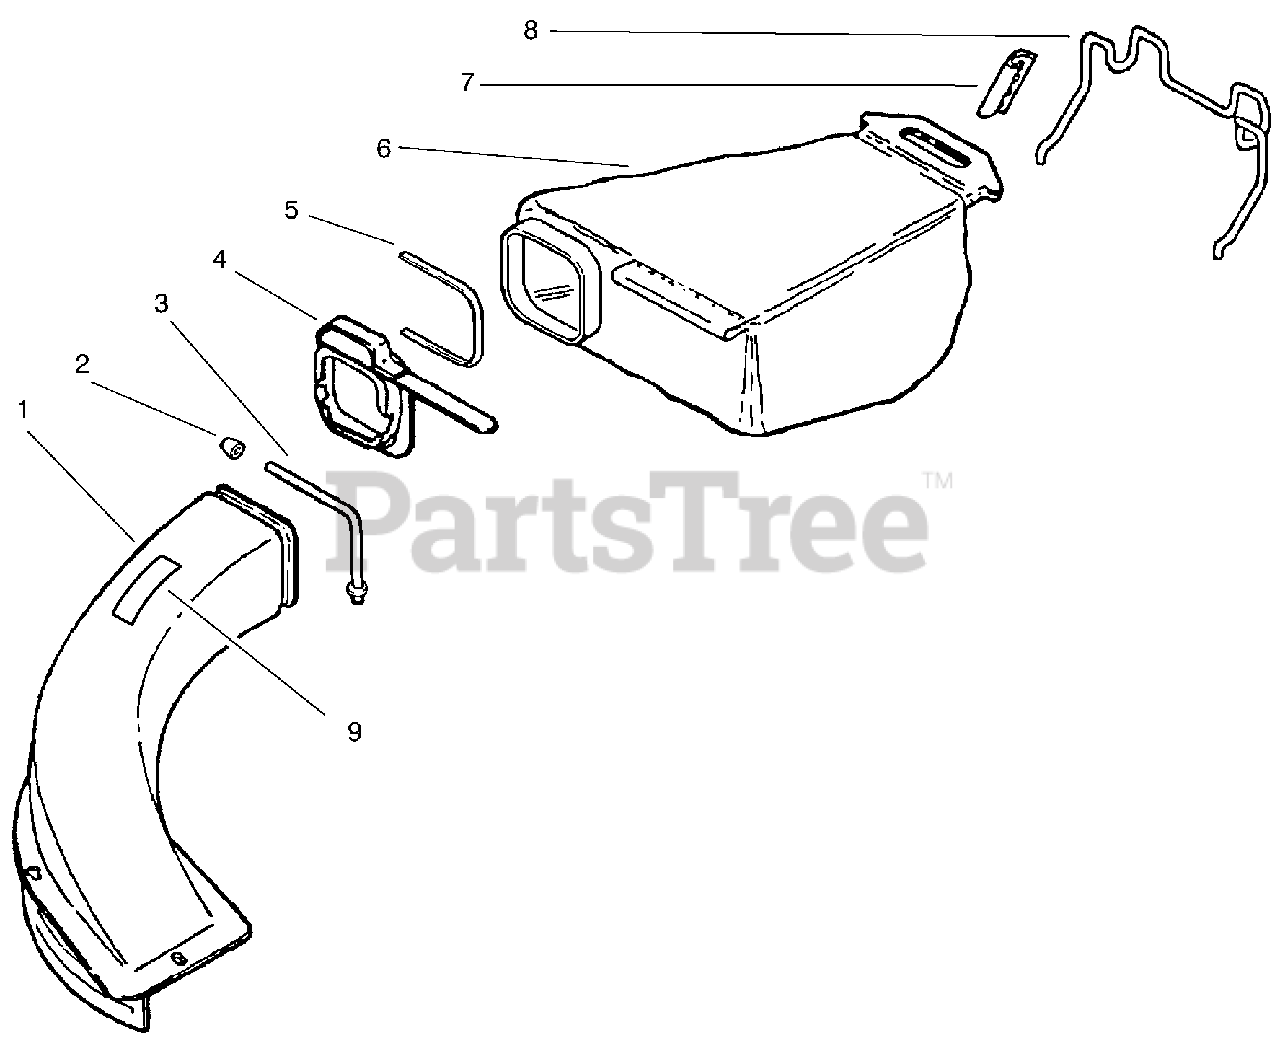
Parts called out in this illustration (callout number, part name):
1	Chute & Support Assembly (Incl. ref.# 2, 3 & 9)
2	Nut-Cap
3	Chute Support
4	Adaptor Assembly
5	Tie Strap
6	Bag Assembly
7	Hanger Clamp
8	Wide Hanger
9	Decal-Danger
